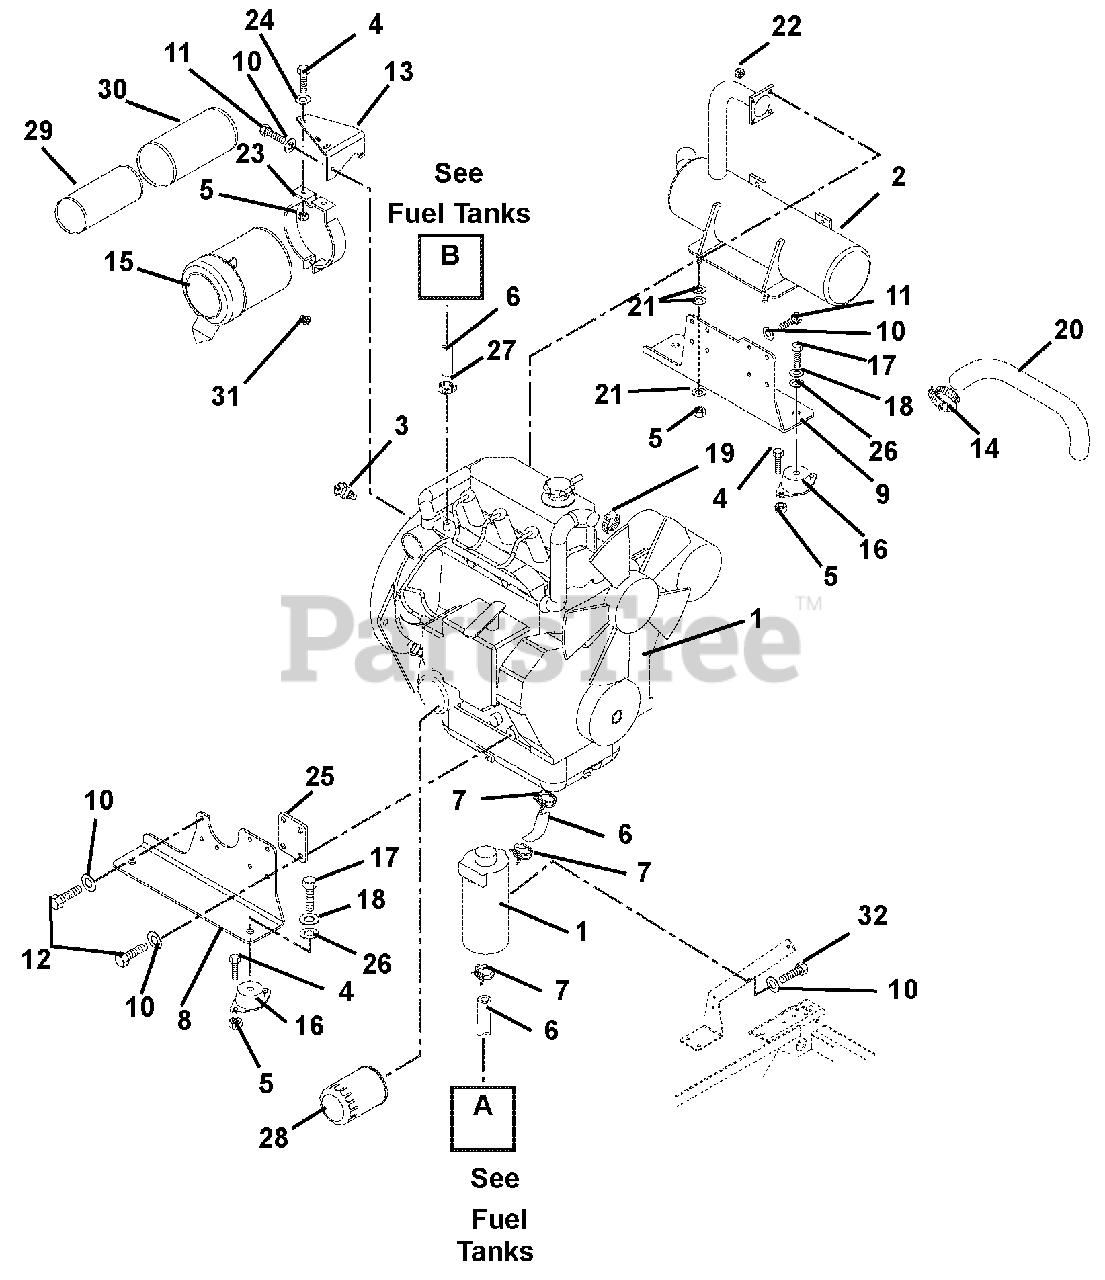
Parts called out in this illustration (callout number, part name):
1	Engine, 27HP Daihatsu Diesel (950D) (316, 322)
2	Muffler (316, 322)
3	Sender, Temperature
4	Bolt, Hex .31-18 x .75 Grade 5
5	Nut, Locking Top Flange .31-18
6	Gas Line, Bulk .31" ID
7	Hose, Clamp
8	Mount, Engine Right Hand
9	Mount, Engine Left Hand
10	Washer, Lock .31 x .078 Regular
11	Bolt, Hex M8-1.25 x 20
12	Bolt, Hex M8 x 1.25 x 25 Grade 8
13	Bracket, Air Cleaner
14	Clamp, 2.50" Dia. Hose
15	Assembly, Air Cleaner
16	Mount, Engine
17	Bolt, Hex .50-20 x 1.00 Grade 5
18	Washer, Locking .50 x .125 Regular
19	Clamp, Hose 1.50 x .81 x 1.42
20	Hose, Air Cleaner (316, 322)
21	Washer, Flat Steel .38 x .875 x .083
22	Nut, Locking, Top M8-1.25
23	Bracket, Air Cleaner Mount
24	Washer, Flat Steel .38 x .875 x .083
25	Spacer, Engine Mounting
26	Washer, Flat Steel .531 x 1.06 x .095
27	Hose Clamp
28	Oil Filter
29	Element, Inner Safety
30	Element, Outer Primary
31	Plug, Pipe .125-27
32	Bolt, Hex M6-1 x 16
